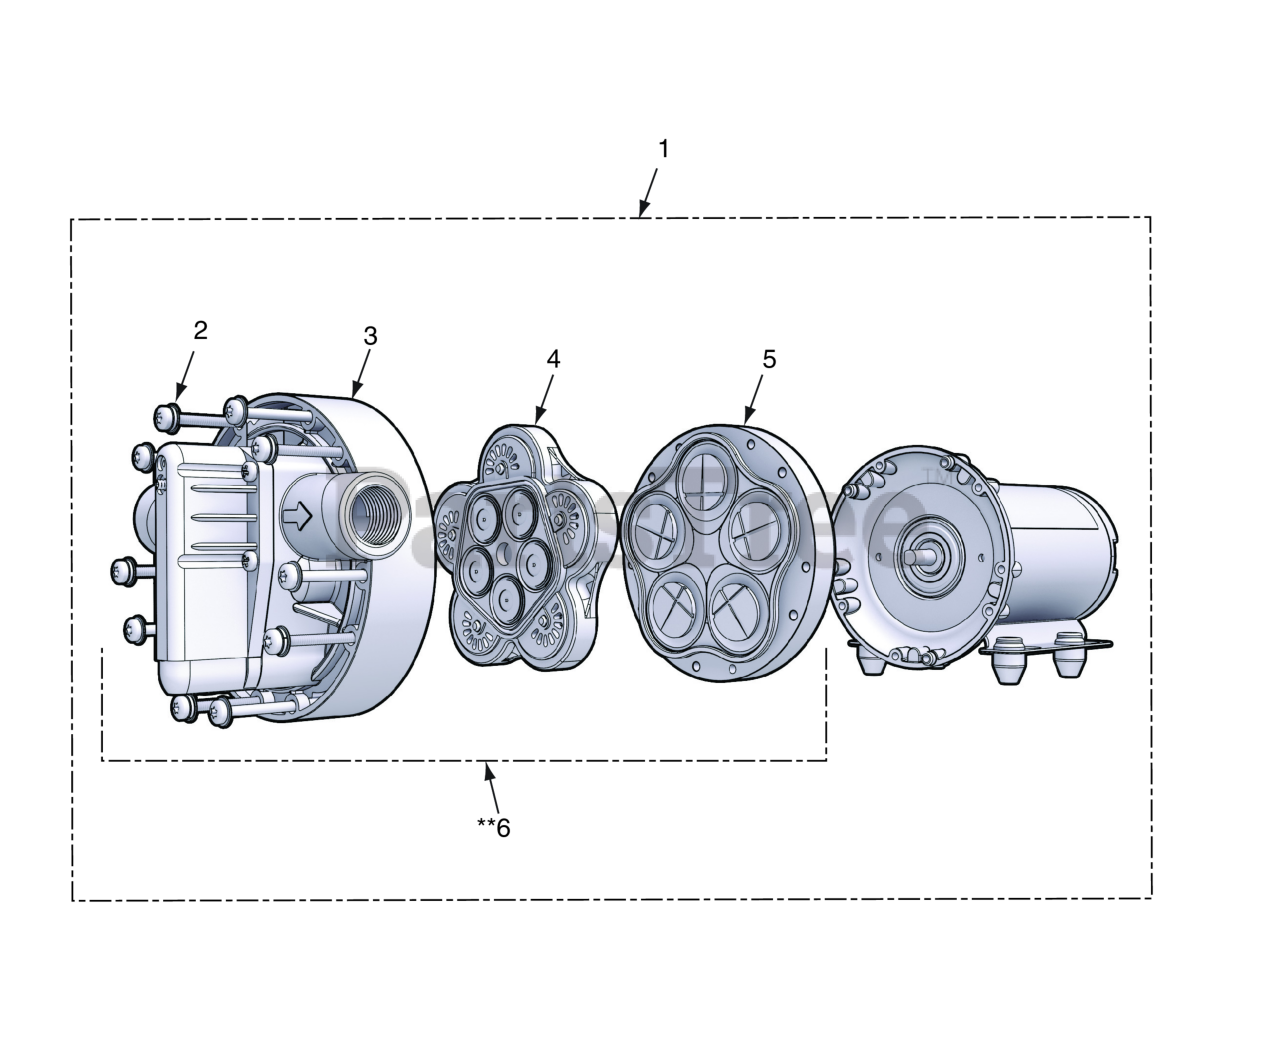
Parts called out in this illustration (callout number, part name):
1	Pump, 12V Electric
2	Screw Kit, Remco (all pumps)
3	Bypass, Upper Housing (5.3 GPM)
4	Valve Housing (5.3 GPM)
5	Lower Housing (5.3 GPM)
6	Pump Head Assembly (7 GPM -Optional Accessory)
